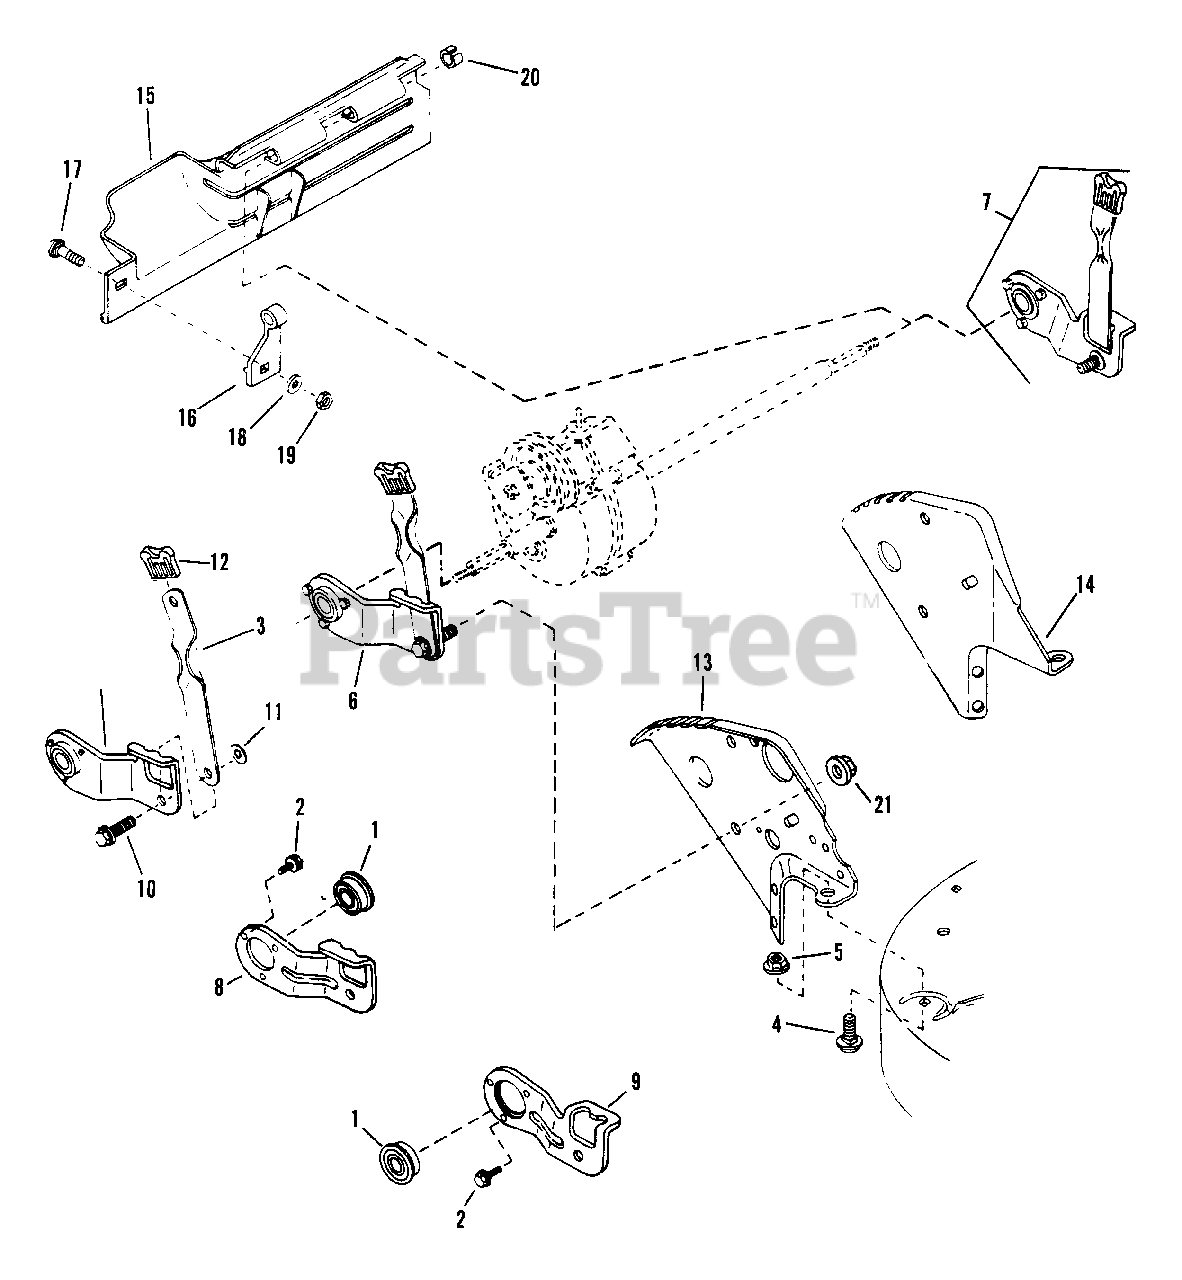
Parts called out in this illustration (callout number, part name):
1	BEARING
2	SCREW, #10-32 x 3/8" Self-Tapping
3	LATCH, Height Adjusting (Long)
4	BOLT, 5/16-18 x 3/4" Short Neck Carriage
5	NUT, 5/16-18 Hex Flange Lock
6	ASSEMBLY, Wheel Arm
7	ASSEMBLY, Wheel Arm
8	ARM, Right Rear Wheel, "P" Models
9	ARM, Left Rear Wheel, "P" Models
10	BOLT, 5/16-18 x 3/4" Shoulder
11	RETAINER, 5/16 Bolt
12	GRIP, Latch
13	BRACKET, Right Rear Wheel
14	BRACKET, Left Rear Wheel
15	GUARD, Rear Foot
16	SUPPORT, Foot Guard
17	BOLT, 1/4-20 x 1/2" Short Neck Carriage, Grade 5
18	WASHER, 1/4 Internal Tooth Lock
19	NUT, 1/4-20 Hex
20	RING, Black
21	NUT, 5/16-18 Hex Flange Lock
